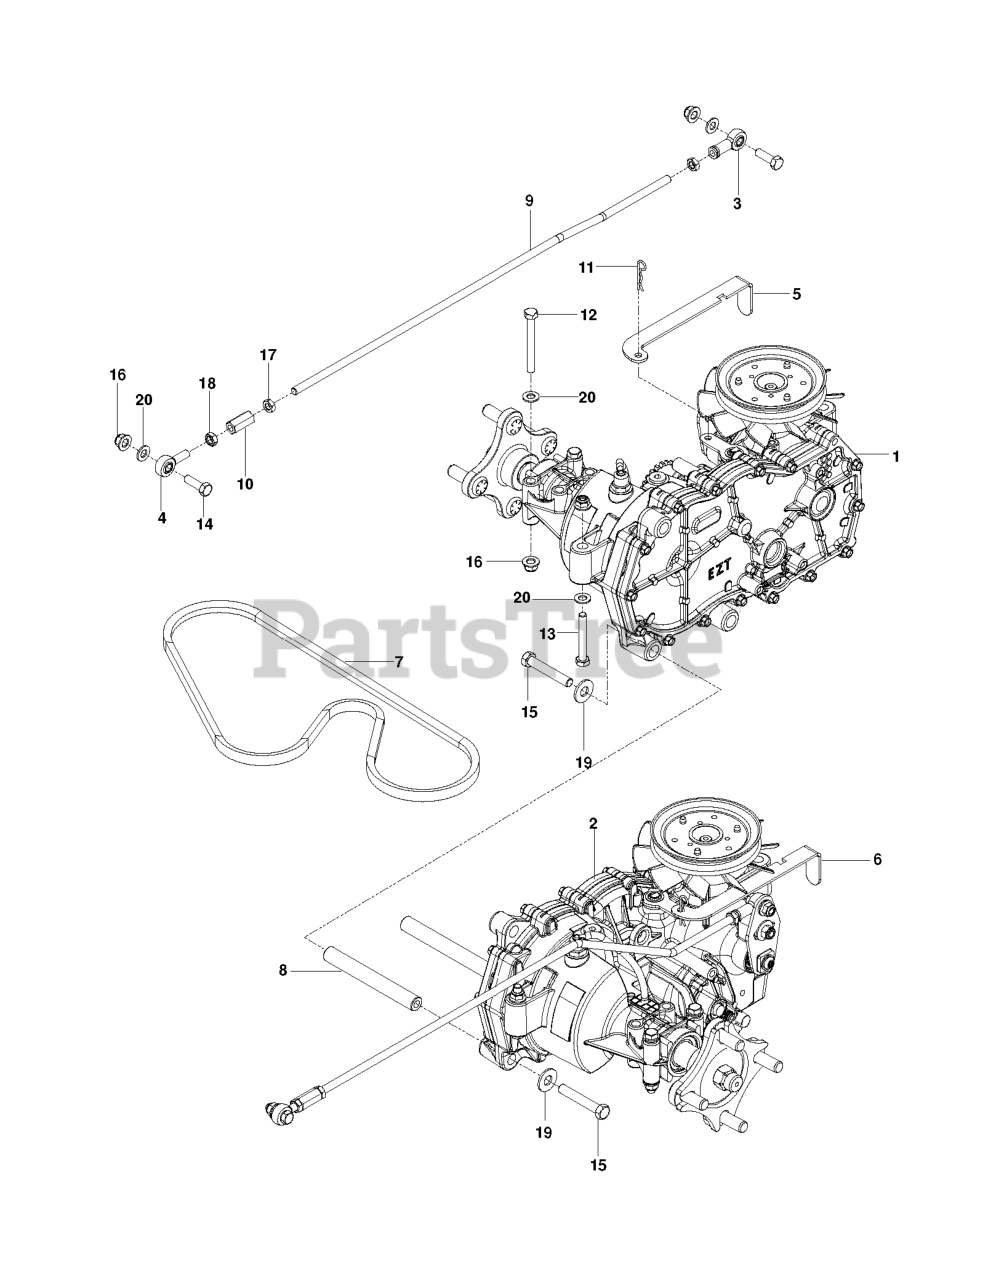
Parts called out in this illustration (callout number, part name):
1	HG_HYDRO RH
2	HG_HYDRO LH
3	RH ROD END
4	RP.ROD.END.LH
5	RELEASE LEVER RH
6	RELEASE LEVER LH
7	BELT, EL 51.O4
8	SPACER, HYDRO
9	CONTROL ROD
10	ROD END COUPLER
11	HAIRPIN #2
12	HCS 5/16C X 2-3/4
14	HCS 5/16C X 1
15	HCS 3/8C X 2 1/4
16	5/16-18 NYLOC FLANGE NUT
17	NUT 5/16-24 UNF HEX JAM
18	NUT 5/16F LEFTHAND
19	WASHER 3/8 FLAT
20	FLAT WASHER 5/16 SAE
